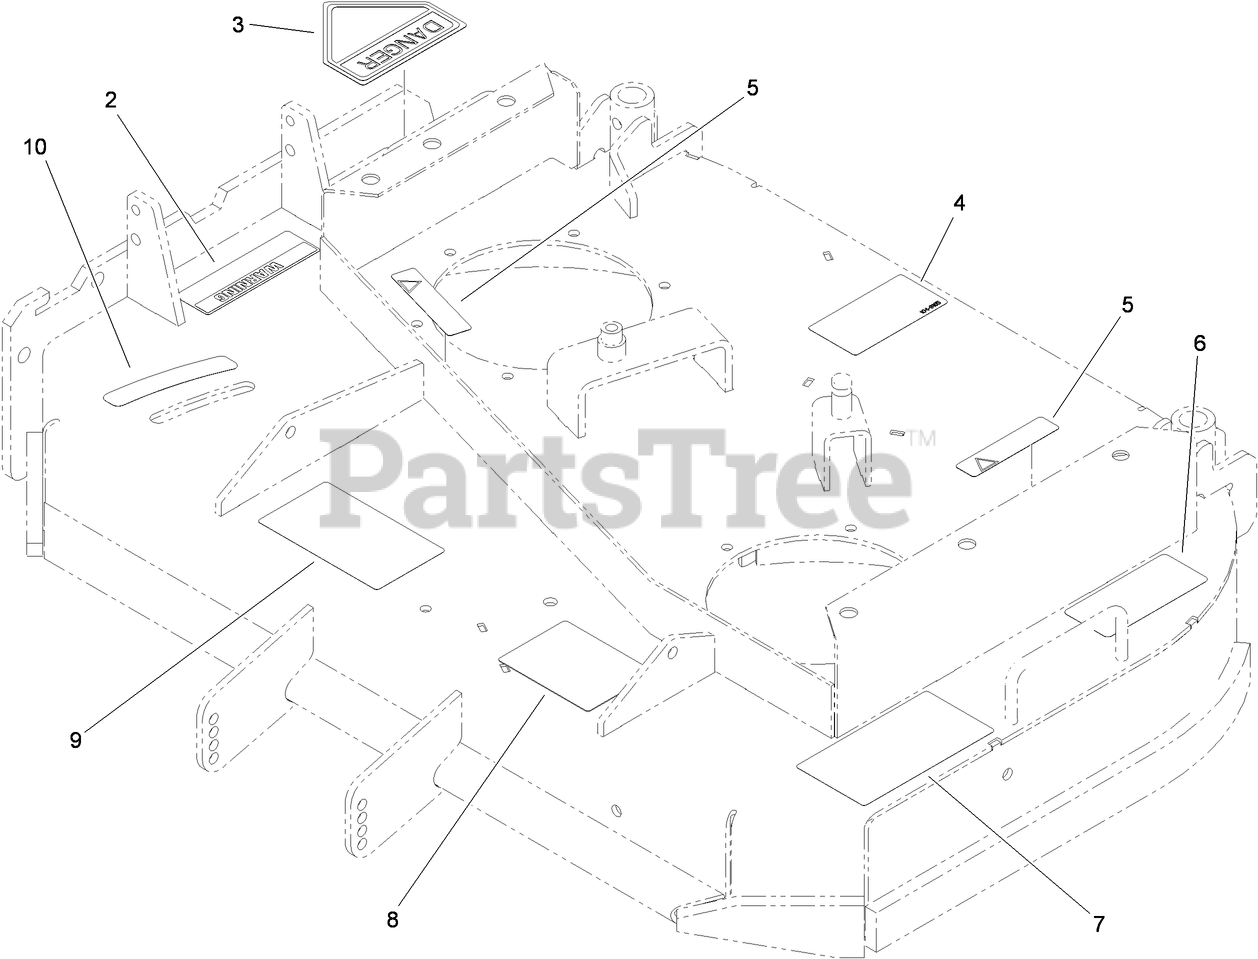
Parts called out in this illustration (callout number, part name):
2	DECAL-WARNING
3	DECAL-DANGER
5	DECAL-COVER, MISSING
6	DECAL-TORQUE
7	DECAL-DANGER, THROWN OBJECT
8	DECAL-SCALP, ANTI
9	DECAL-ADJUSTMENT, BAFFLE
10	DECAL-SETTING, BAFFLE
